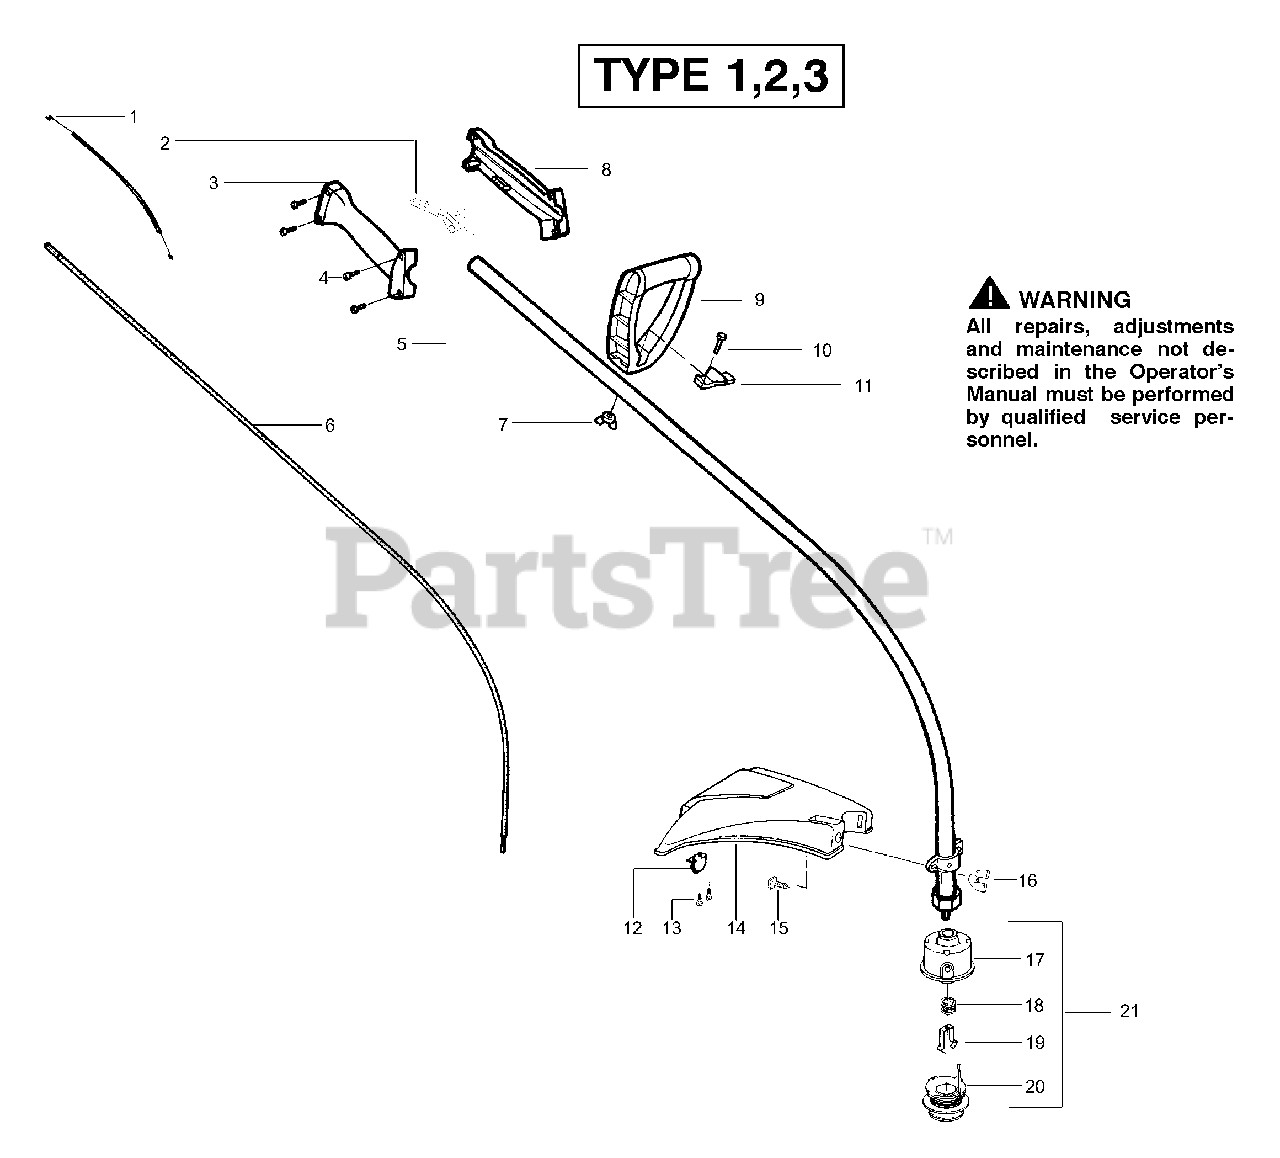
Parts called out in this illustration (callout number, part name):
1	Assy-Throttle Cable
2	Trigger - Throttle
3	Throttle Hsg. (Right)
5	Drive Shaft Hsg. Ass'y
6	Drive Shaft - Flex
7	Wingnut
8	Throttle Hsg. (Left)
9	Assist Handle
10	Bolt-Handle/Shield
11	Clamp-Handle Assist
12	Line Limiter
13	Screw-Line Limiter
14	Shield Kit Ass'y.
15	Bolt-Handle/Shield
16	Wingnut
17	Assy-Hub
18	Spring-Return
19	Retainer-Spool
20	Accy-Wound Spool
21	Accy-Cutting Head
